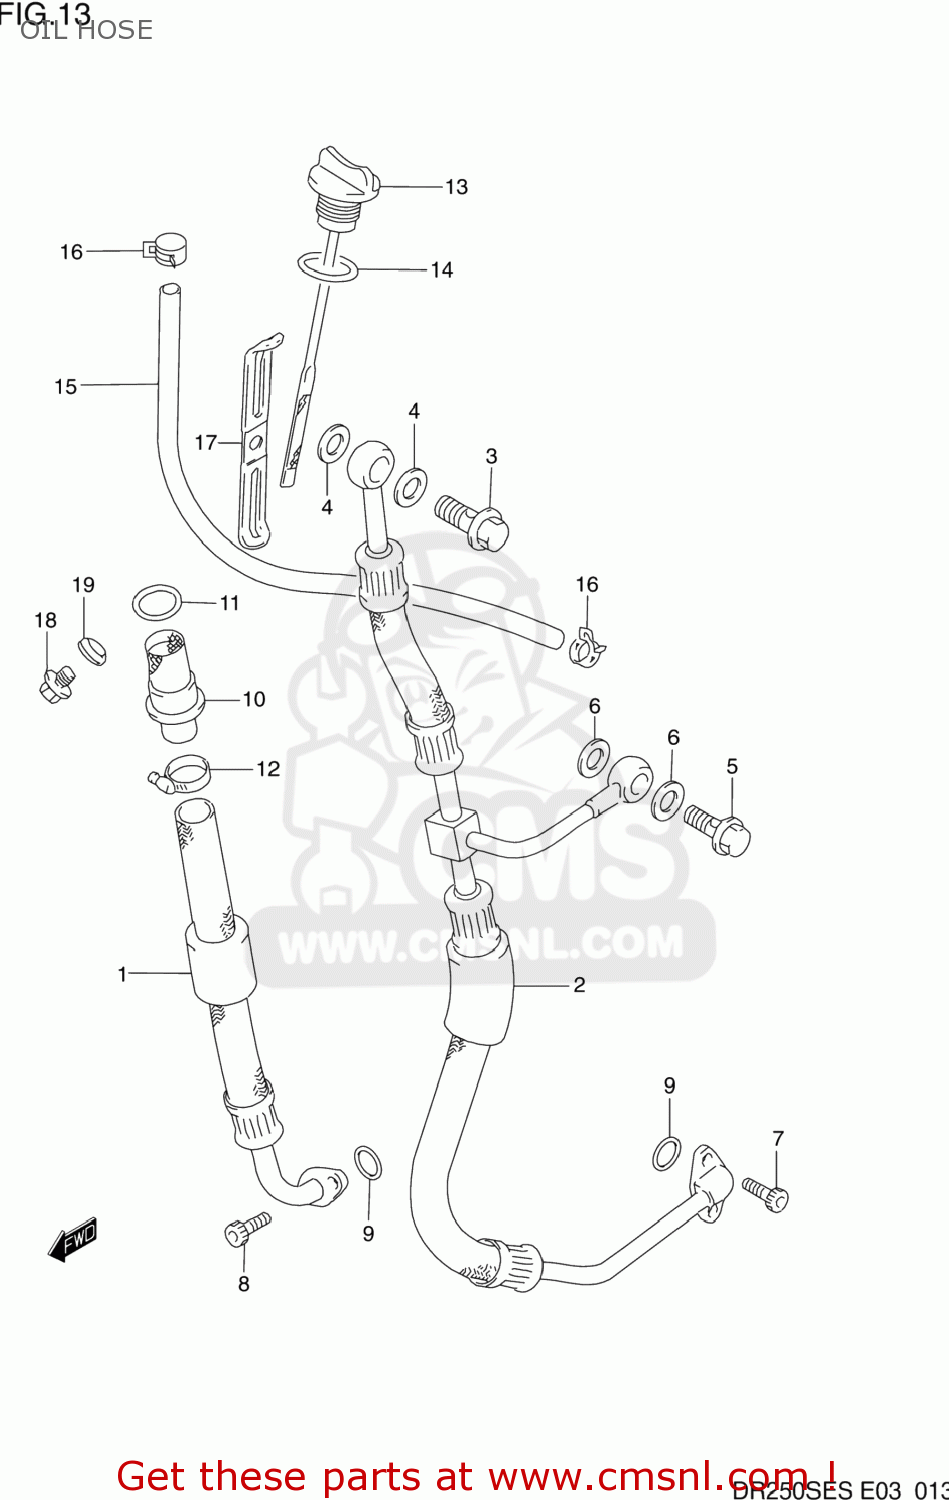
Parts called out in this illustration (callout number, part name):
1	HOSE,OIL TANK INLET
2	HOSE,OIL
3	BOLT UNION
4	GASKET(16X22X2) (NAS)
5	BOLT UNION
6	GASKET(12X17X1) (NAS)
7	BOLT
8	BOLT
9	O RING(D:2.4,ID:12.3)
10	STRAINER,FRAME HEAD UNDER
11	O RING(D:3.1,ID:22.7)
12	CLAMP
13	GAUGE ASSY,OIL LEVEL
14	O RING(D:3.1,ID:16.8)
15	HOSE,OIL COOLER,UPPER
16	CLIP
17	CLAMP(L:55)
18	PLUG
19	GASKET(10X14X3.6) (NAS)
